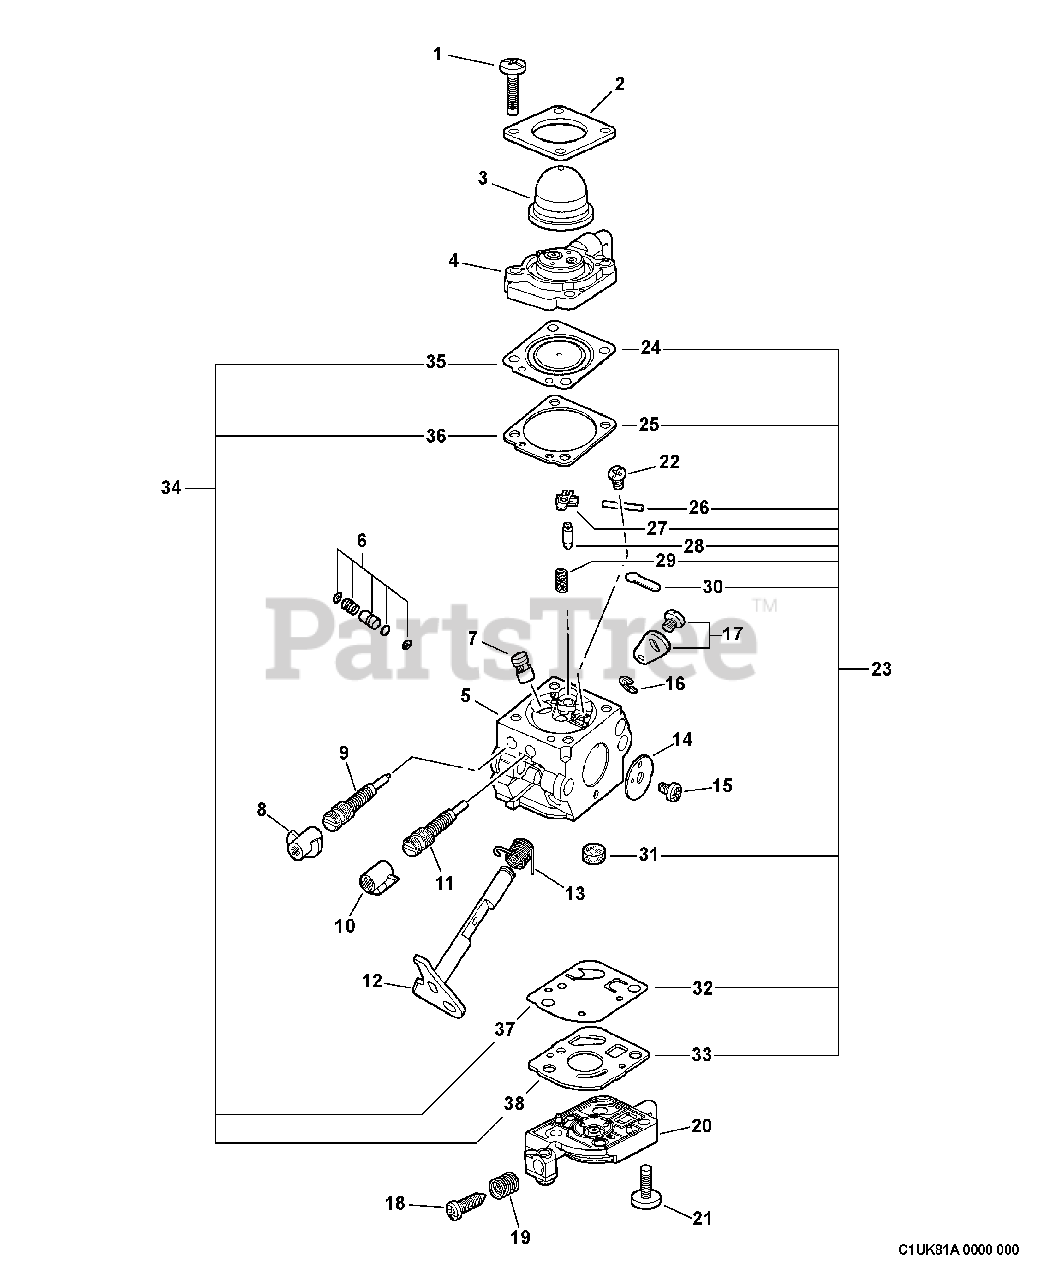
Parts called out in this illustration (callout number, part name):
1	SCREW, RETAINER
2	RETAINER, PURGE BULB
3	BULB, PURGE
4	BASE, PURGE
5	BODY, CARBURETOR
6	PUMP KIT
7	NOZZLE, CHECK VALVE
8	CAP, LIMITER
9	NEEDLE - HIGH SPEED
10	CAP, LIMITER
11	NEEDLE - LOW SPEED
12	SHAFT, THROTTLE
13	SPRING, RETURN
14	VALVE, THROTTLE
16	RING, RETAINING
17	THROTTLE LEVER KIT
18	SCREW, IDLE ADJUST
19	SPRING, IDLE ADJUST
20	BASE, PURGE
21	SCREW, PUMP COVER
22	SCREW, METERING LEVER PIN
23	REPAIR KIT
24	DIAPHRAGM, METERING
25	GASKET, DIAPHRAGM
26	PIN, METERING LEVER
27	LEVER, METERING
28	VALVE, INLET NEEDLE
29	SPRING, METERING LEVER
30	PLUG, WELCH
31	STRAINER
32	DIAPHRAGM, PUMP
33	GASKET, PUMP
34	DIAPHRAGM/GASKET KIT
35	DIAPHRAGM, METERING
36	GASKET, DIAPHRAGM
37	DIAPHRAGM, PUMP
38	GASKET, PUMP
